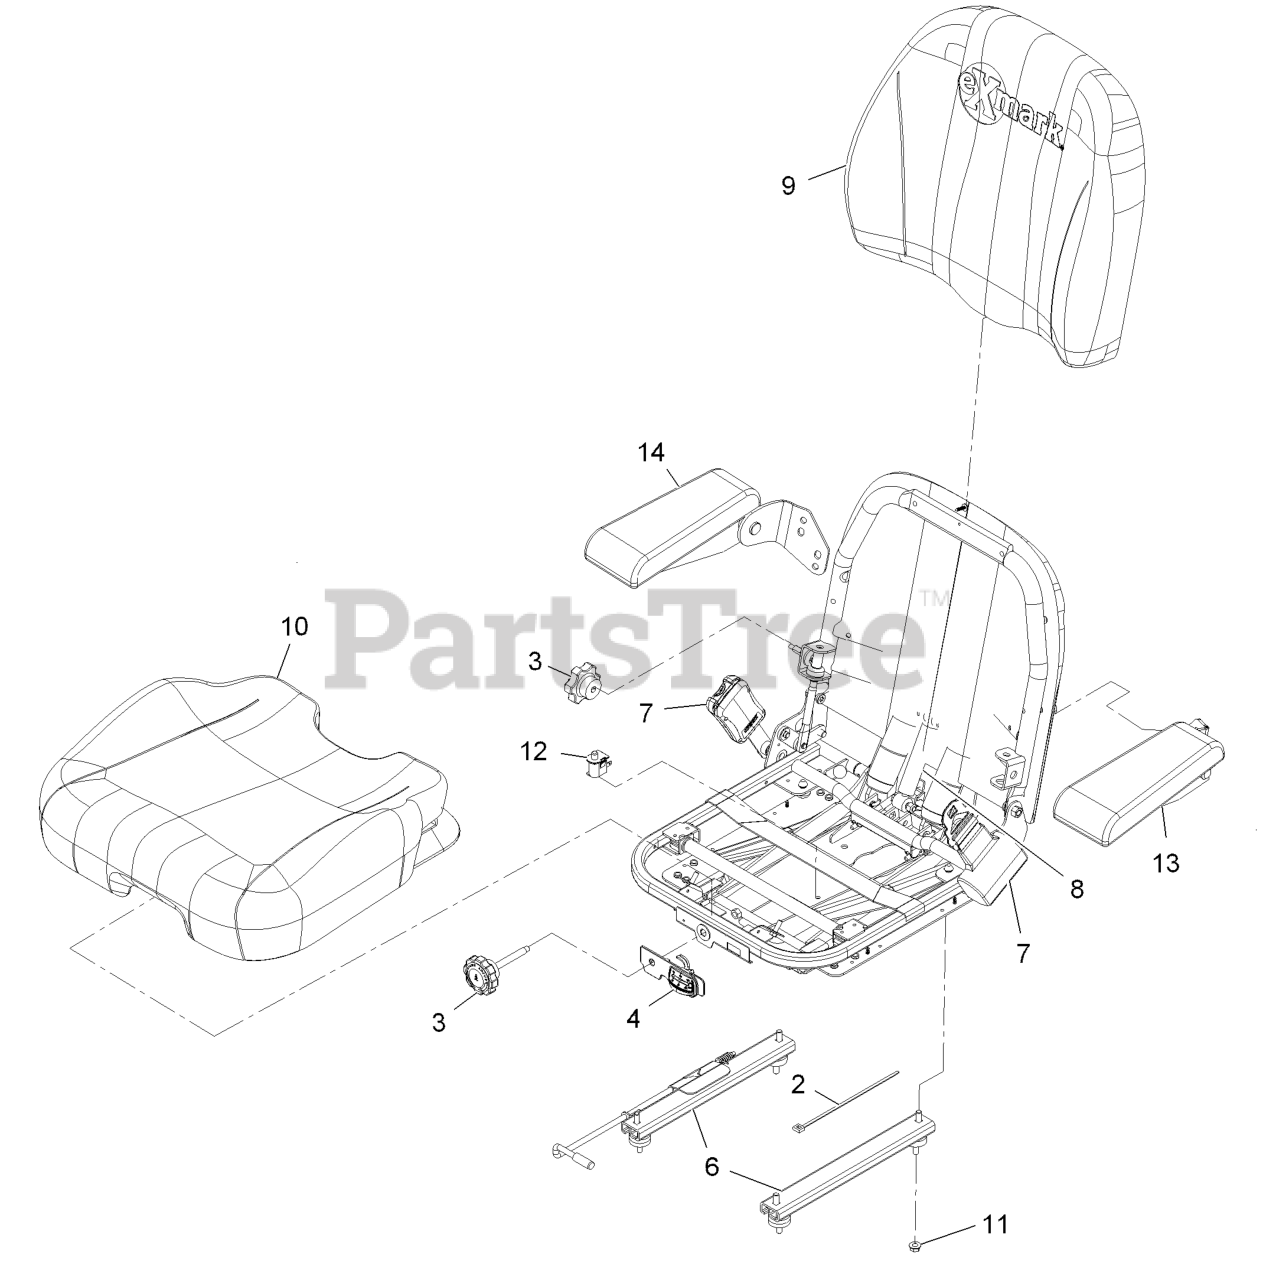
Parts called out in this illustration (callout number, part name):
2	TIE-PLASTIC
3	KNOB KIT
4	WEIGHT INDICATOR KIT
6	SEAT TRACK KIT
7	SEAT BELT KIT (SHORT)
8	SHOCK ABSORBER KIT
9	KIT,BACK CUSHION AND COVE
10	KIT,BOTTOM CUSHION AND CO
12	SWITCH-BAIL
13	ARM REST ASM,SUSP.SEAT LH
14	ARM REST ASM,SUSP.SEAT RH
